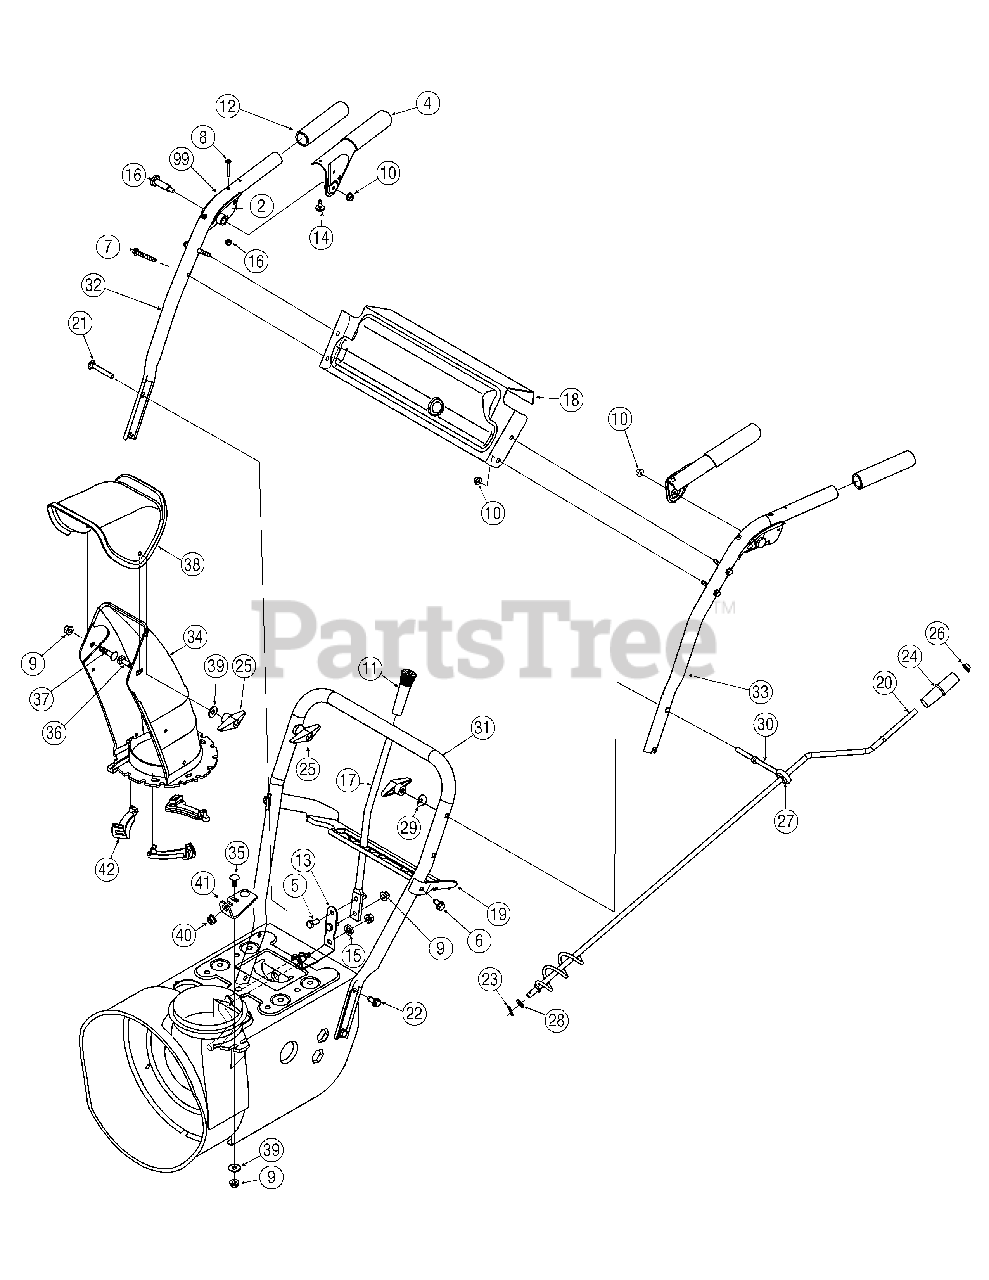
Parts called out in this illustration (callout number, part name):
1	Handle Ass’y, Lock LH
2	Handle Ass’y, Lock, RH
3	Handle Ass’y, Engagement, RH
4	Handle Ass’y, Engagement, LH
5	Screw, Self-tapping, 5/16-18, .625
6	Screw, Self-tapping, 5/16-18, 1.0
7	Screw, Self-tapping, 1/4-20, 1.50
8	Screw, Machine, #10-24, 1.375
9	Nut, Flange Lock, 5/16-18, Nylon
10	Nut, Flange Lock, 1/4-20, Nylon
11	Grip, 0.5 ID x 3.45
12	Grip, 1.0 ID x 5.0
13	Spring Lever, Shift
14	Bumper, Rubber, .62 OD x .22
15	Washer, Flat, .350 sq. x .72 x .134
16	Screw, Shoulder, .437 x 1.345, 1/4-20
21	Screw, Carriage, 5/16-18, 2.25, Gr5
22	Screw, 5/16-18, 0.75, Gr5
23	Pin, Cotter, .072 x 1.13
24	Crank Knob, 1.0 Diameter x 3.2,
25	Knob Assembly, Wing Nut, 5/16-18
26	Cap, Push, 3/8 Rod
27	Grommet, .44 ID x .94 OD x
28	Washer, Flat, .375 x .738 x .063
29	Washer, Saddle, 320 x .93 x .
30	Eye Bolt, Chute Crank
34	Chute, Lower, 5.0 Diameter
35	Bolt, Carriage, 5/16-18, 1.0
36	Bolt, Carriage, 5/16-18, 1.0, Custom
37	Bolt, Carriage, 5/16-18, .750
38	Chute, Upper, w/ Label
39	Washer.349 ID x .879 OD x .063
40	Bushing, Plastic, .380
42	Chute, Flange Keeper
